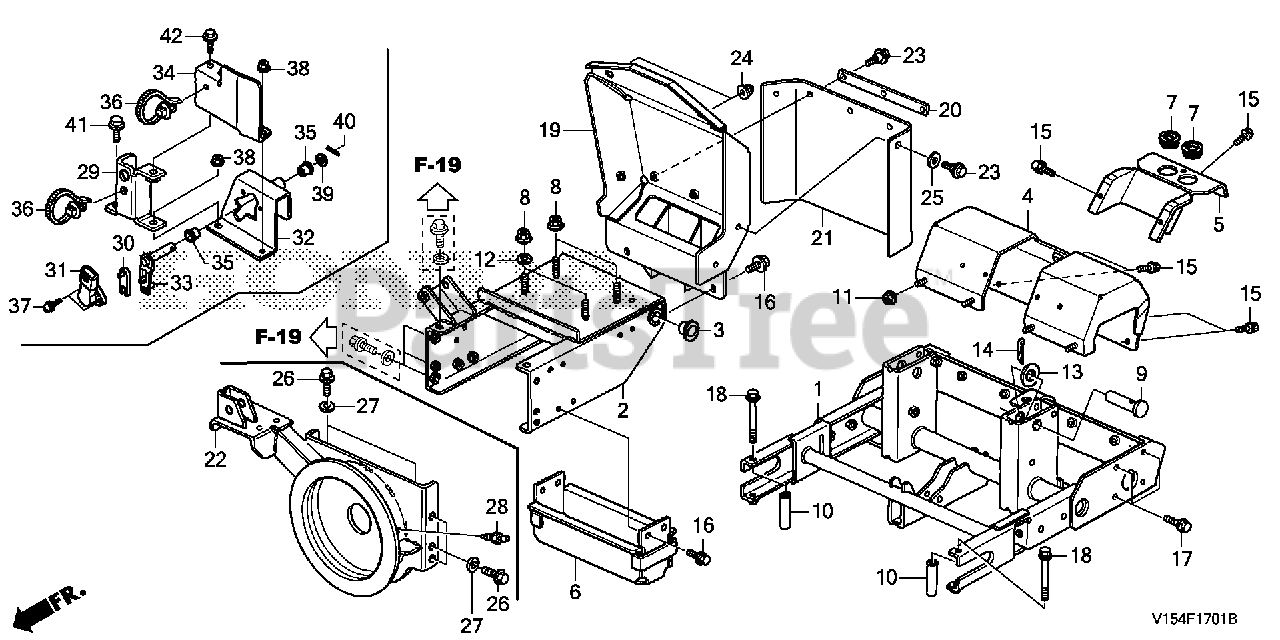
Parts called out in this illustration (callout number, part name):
1	FRAME, CRAWLER
2	FRAME, MAIN
3	BUSH, FRAME
4	COVER, MOTOR
5	COVER, MOTOR (UPPER)
6	COVER, BELT
7	GROMMET, TURN SIGNAL (NOT AVAILABLE)
8	NUT, FLANGE (10MM)
9	PIN, FRAME
10	COLLAR, FRAME CRAWLER
11	NUT, FLANGE (6MM)
12	WASHER, PLAIN (10MM)
13	WASHER, PLAIN (20MM)
14	PIN, COTTER (3.0X35)
15	BOLT, FLANGE (6X12) Use up to Engine SN 1543277.
16	BOLT, FLANGE (8X16) Use from Engine SN 1000016.
17	BOLT, FLANGE (8X20) Use up to Engine SN 1609606.
18	BOLT, FLANGE (8X85)
19	GUARD, FAN COVER
20	PLATE, ENGINE GUARD SEAL
21	SEAL, ENGINE GUARD
22	STAY, HOUSING *NH1* (BLACK)
23	BOLT, SPLASH GUARD
25	WASHER, PLAIN (10MM)
26	BOLT, FLANGE (10X20)
27	WASHER, PLAIN (10MM)
28	NIPPLE, GREASE (A.T6) (M6X1.0)
29	STOPPER, CLUTCH
30	ARM, TURN LEVER
31	SENSOR ASSY., ANGLE
32	BRACKET, ROLLING SENSOR
33	SHAFT, ROLLING SENSOR
34	GUARD, FR. COVER
35	BUSH, CLUTCH LEVER
36	CLIP, HARNESS BAND (164.5MM) (BROWN)
37	SCREW-WASHER (5X18) (NOT AVAILABLE)
38	NUT, FLANGE (8MM)
39	WASHER, PLAIN (8MM)
40	PIN, COTTER (2.0X22)
40	PIN, COTTER (2.0X35)
41	BOLT, FLANGE (8X16) Use from Engine SN 1000016.
42	BOLT, FLANGE (8X20) Use up to Engine SN 1609606.
